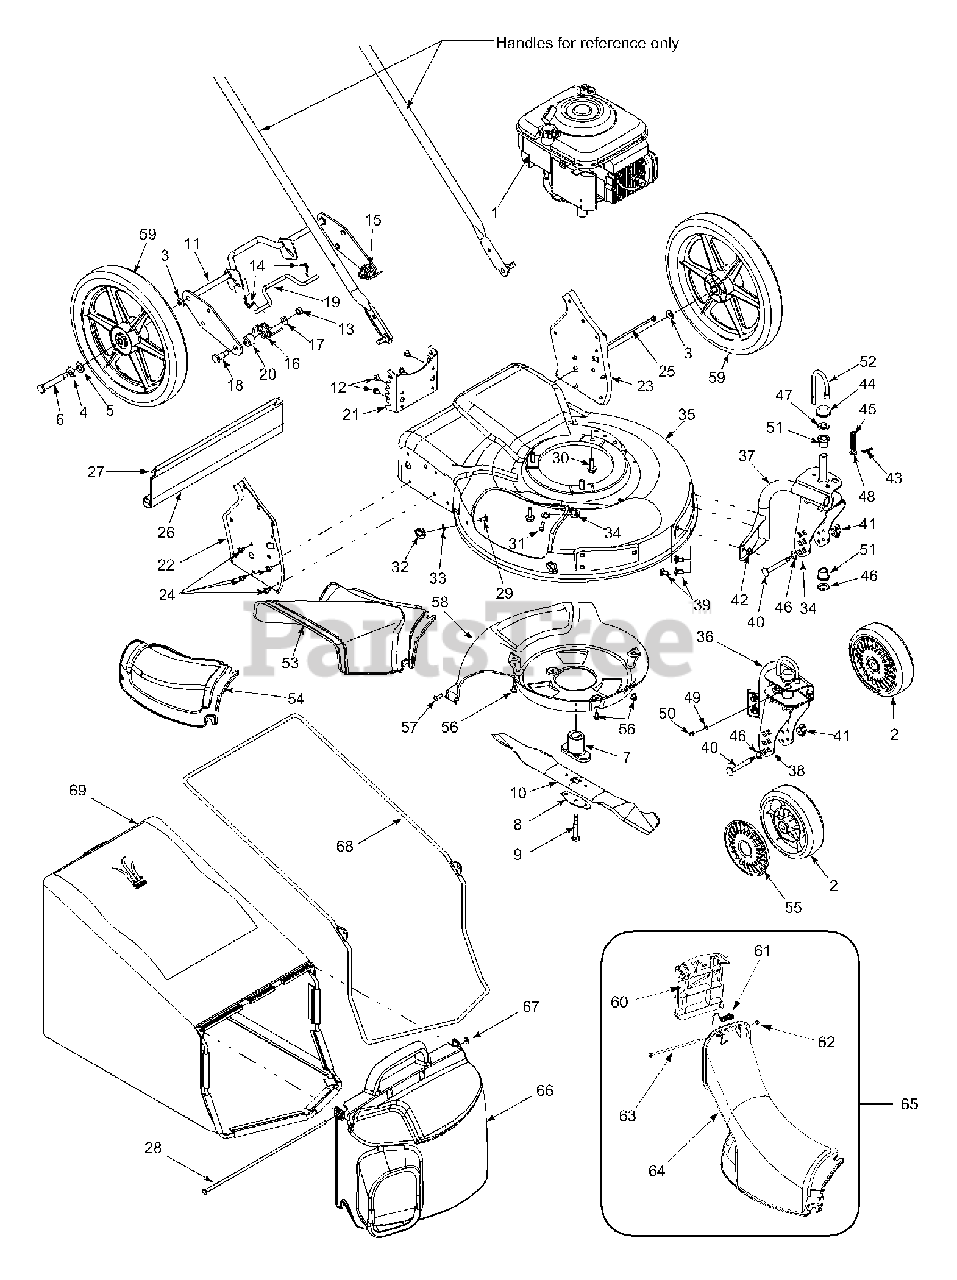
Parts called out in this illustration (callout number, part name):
1	Engine
2	Wheel, Front Caster 7 X 2
3	Bell Washer .401 X .870 X .063
4	Spring Washer .50 I.D. x 1.0 x .022
5	Flat Washer .510 x 1.0 x .060
6	Shoulder Screw .500 x 2.62: 3/8 -16
7	Blade Adapter
8	Blade Bell Support
9	Hex Bolt 3/8 - 24 x 2.5 Gr. 8
10	Blade 21", Mulching
11	Hi-Wheel Height Adj. Support
12	AB Screw 1/4-14 x .50
13	Hex Nut 3/8 -16
14	Torsion Spring
15	Torsion Spring, RH
16	Torsion Spring, LH
17	Bell Washer .401 x .870 x .063
18	Shoulder Screw .500 x .840
19	Handle, Height Adjustment
20	Spacer .500 x 1.0 x .600
25	Cable Tie
26	Trail Shield
27	Trail Shield Wire
28	Brass Bag Pivot Rod
29	Carriage Screw
30	TT Screw 3/8 -16 x 1.00
31	Carriage Screw 1/4-20 x .75
32	Wing knob
33	Push Nut
39	Carriage Bolt 5/16-18 x .62
40	Caster Axle .374 x 2.59
41	Wing Knob
42	Flange Nut 5/16-18 Gr.5
43	Hairpin Clip
44	Push Cap
45	Compression Spring
46	Wave Washer .530 I.D. x .780 O.D.
47	Flat Washer, .604 x 1.12 x .125
48	Flat Washer .330 I.D. x .630 x .06
49	Flat.Washer. .203 I.D. x .403 x .040
50	Lube Fitting
51	Flange Bearing
52	Lock Pin, Front Wheel
53	Discharge Chute
54	Mulching Cover
55	Hubcap
56	Hex Screw, TT 1/4-20 x .375
57	Self-tapping Screw (Hi-Lo)
58	Rear Baffle
59	Hi-Wheel 14 X 2
60	Chute Door
61	Torsion Spring
62	Push Cap
63	Pivot Rod
64	Discharge Chute
65	Chute Assembly
66	Top Discharge Grass Bag Cover
67	Cap Nut
69	Grass Bag, Sail w/ Sprig
